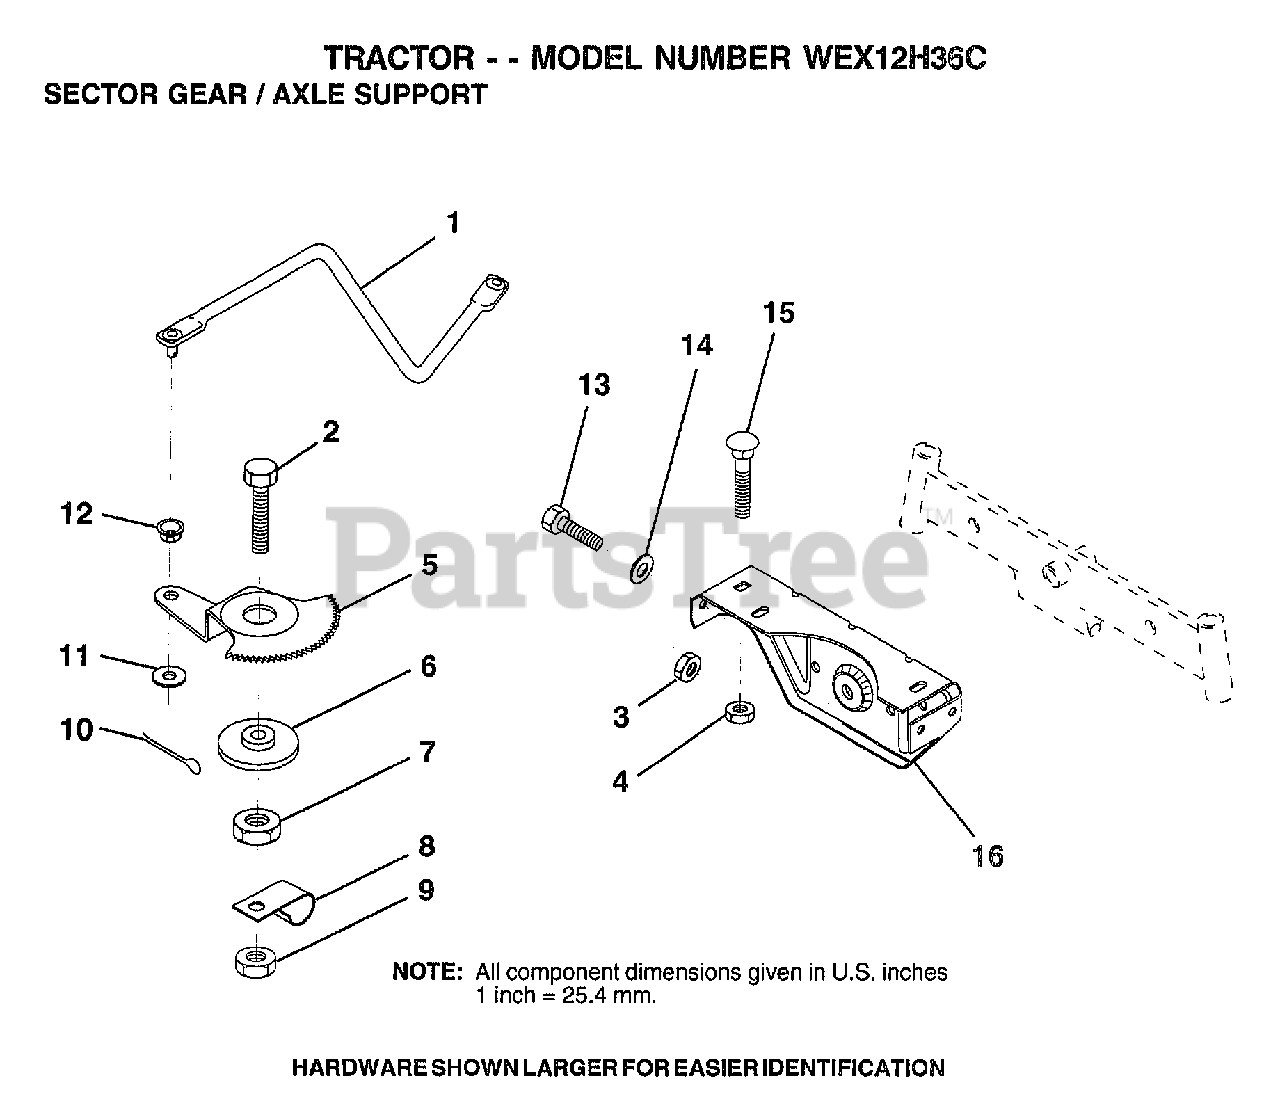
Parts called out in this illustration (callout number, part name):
1	DRAG LINK
2	"BOLT,HEX"
5	GEAR SECTOR
6	BUSHING
7	NUT
8	CLIP INSULATOR
9	NUT LTV
10	COTTER PIN
11	WASHER
12	BUSHING.DRAGLINK
13	BOLT
14	WASHER
15	BOLT
16	SUPT AXLE FRONT
